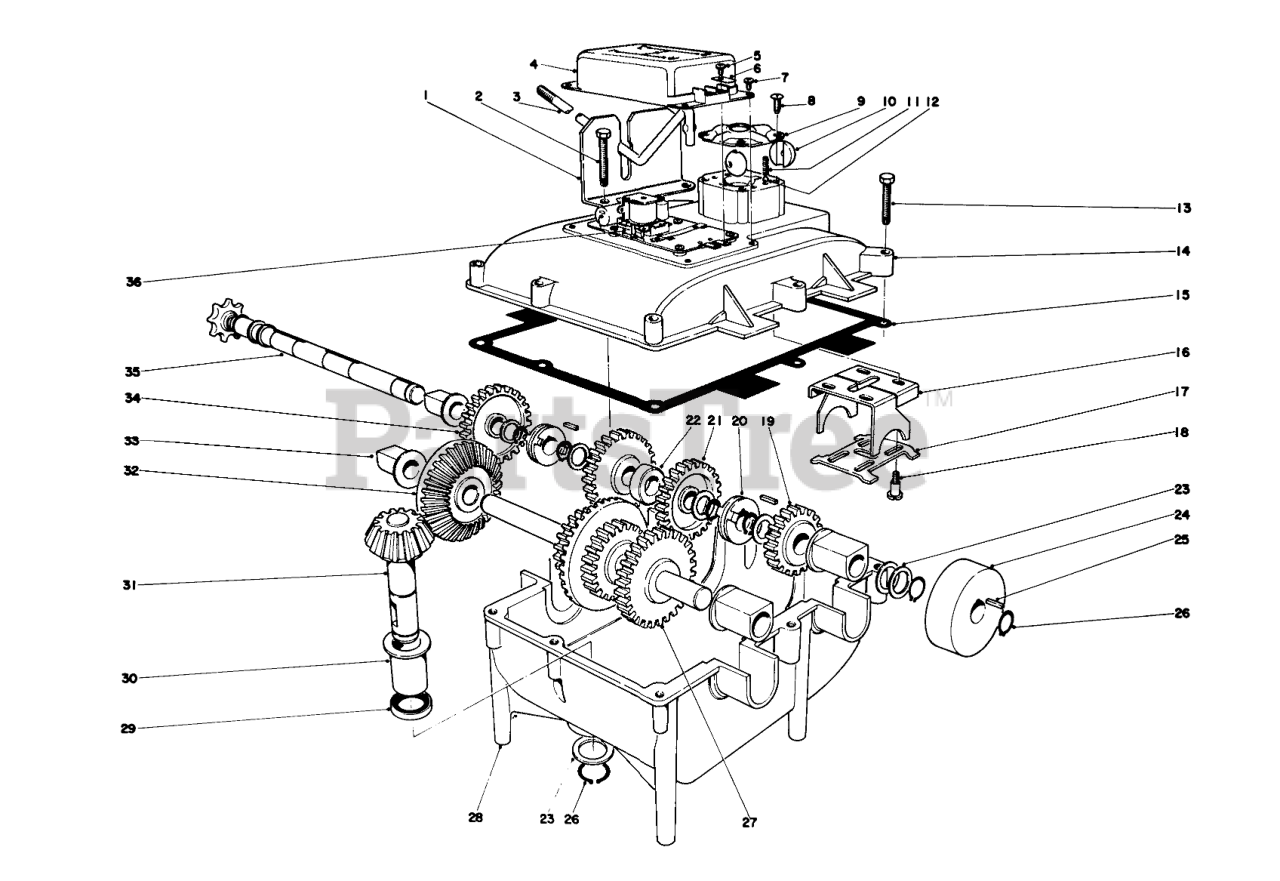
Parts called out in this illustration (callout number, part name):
1	Bracket Shift
3	Shift Rod
4	Housing Ign.-interlock
6	Terminal
9	Cap Shift
10	Ball Shift Segment
11	Spring
12	Ball-Detent
14	Cover-Gear Housing
15	Gasket
16	Yoke Shift
17	Plate-Backing
18	Screw Shoulder
19	Gear-24 Teeth
20	Dog Driving
21	Gear-30 Teeth
22	Spacer
23	Flat Washer
24	Brake Drum
26	RING-SNAP, EXTERNAL
27	Assembly-Drive Shaft
28	Housing Gear
29	Seal Grease
30	Bushing
31	Assembly-Pinion Shaft
32	Bevel Gear
33	Bearing
34	Gear 36 Tooth
35	Shaft Sprocket
36	Assembly Ignition Interlock
